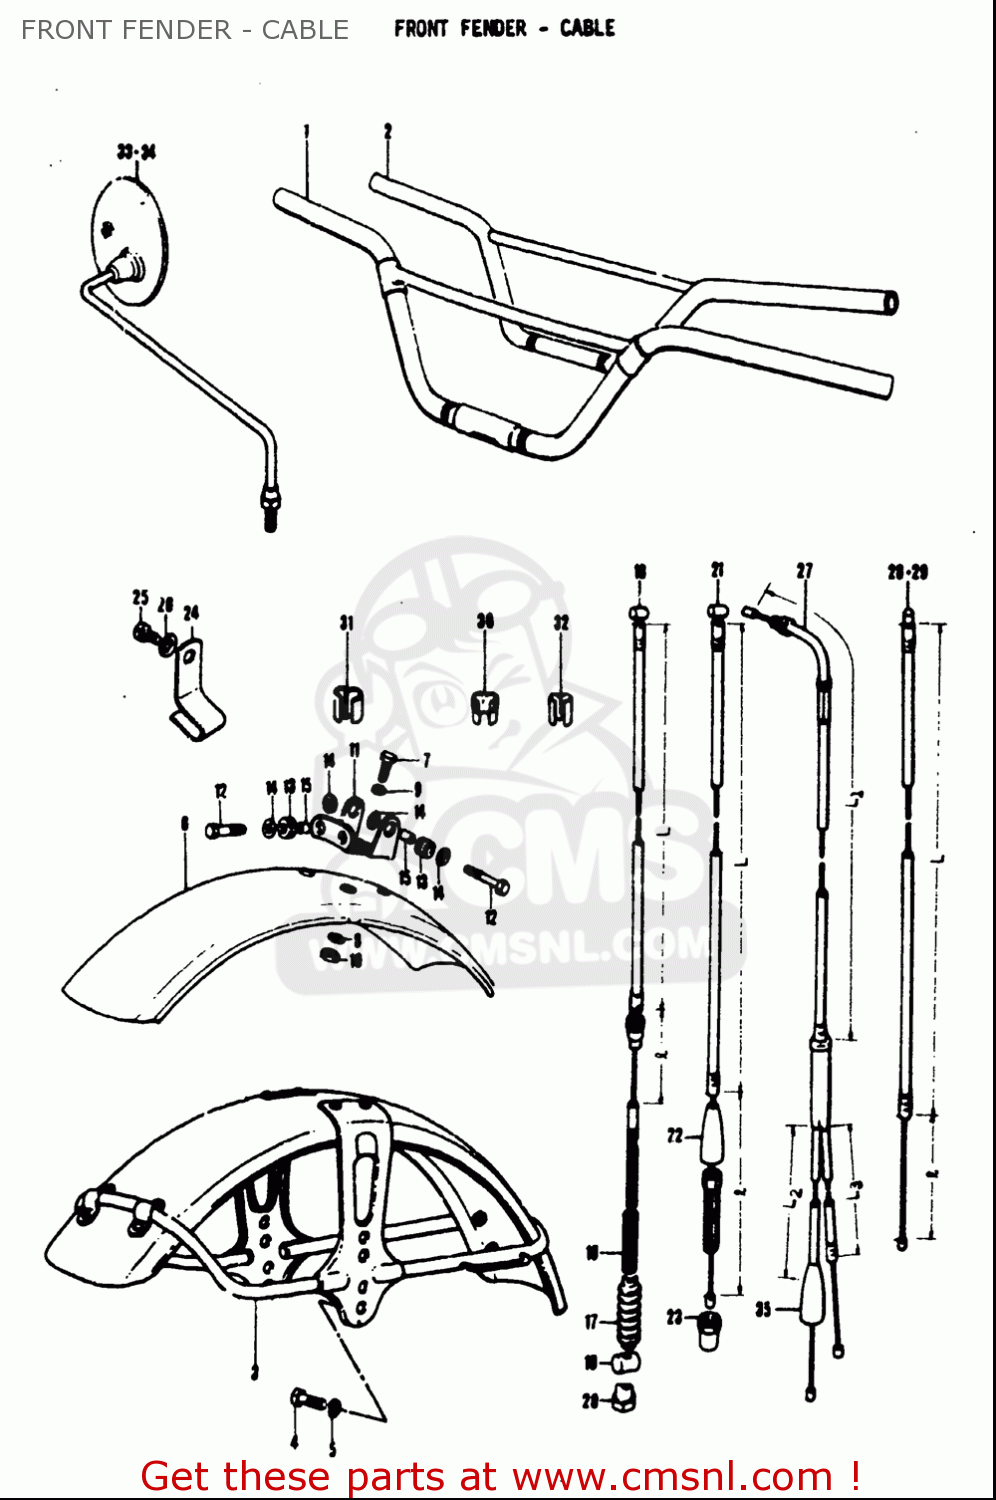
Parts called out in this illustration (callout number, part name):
2	HANDLEBAR
4	BOLT
5	WASHER,LOCK
7	BOLT
8	WASHER,LOCK
9	WASHER
10	NUT
11	BRACE,FRONT FENDER
12	BOLT
13	CUSHION
14	WASHER(6.5X20X1.2)
15	SPACER,6.5X9X7
16	CABLE ASSY,FR BRAKE(L:1175)
17	SEAL,DUST(7X16X75)
18	SPRING
19	BRAKE ROD LEVER
20	BRAKE ROD ADJ N
21	CABLE ASSY,CLUTCH
22	SEAL,DUST(7X18X30)
23	NUT
25	BOLT
26	WASHER,LOCK
27	CABLE ASSY,THROTTLE
28	CABLE,STARTER
29	CABLE,STARTER
30	CLIP
32	CLIP
33	MIRROR ASSY,RE
35	SEAL,DUST(7X18X30)
